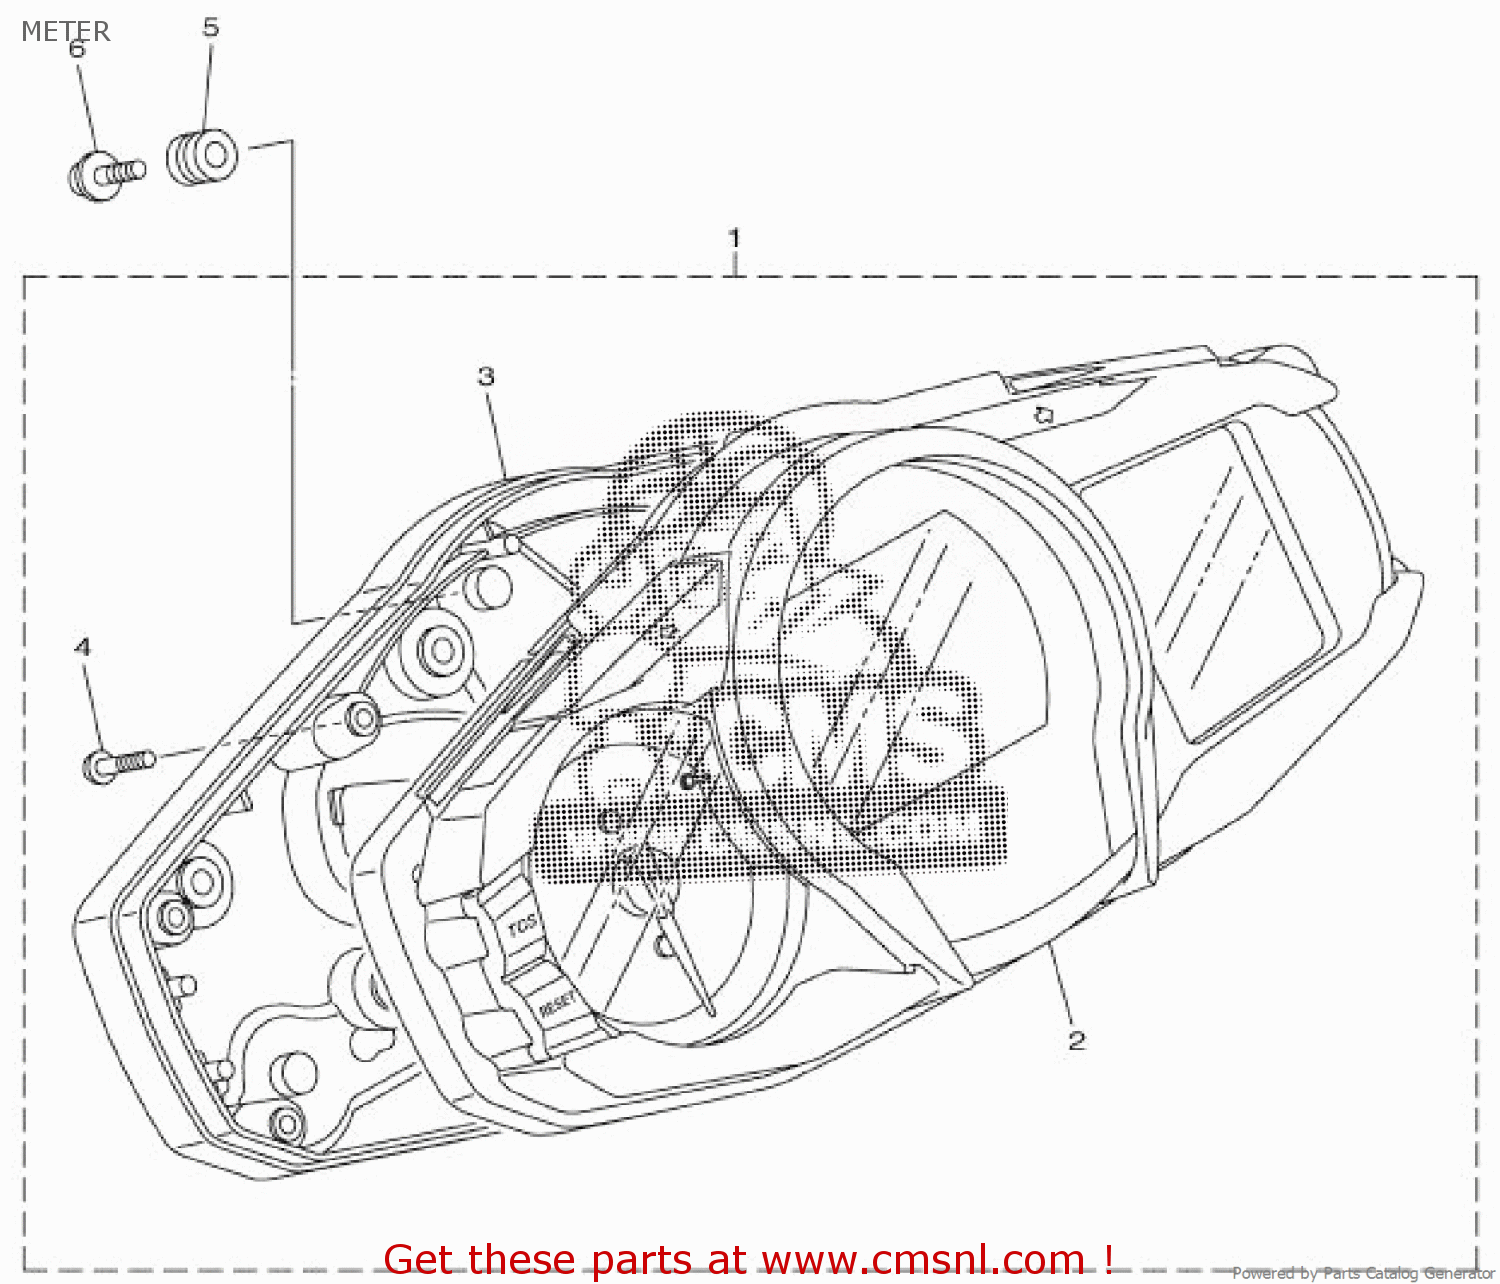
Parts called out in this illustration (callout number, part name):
1	METER ASSY
2	CASE, METER UPPER
3	CASE, UNDER
4	SCREW, TAPPING
5	DAMPER
6	SCREW, TAPPING
